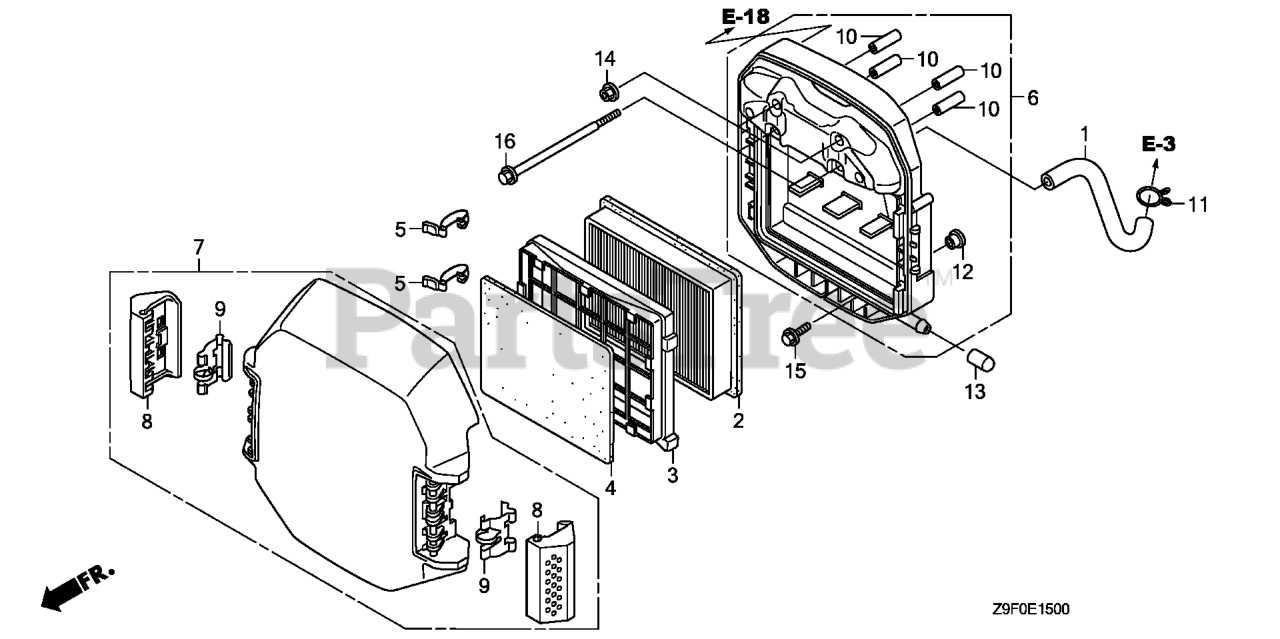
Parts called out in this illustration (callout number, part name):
1	TUBE, BREATHER
2	ELEMENT, AIR CLEANER
3	HOLDER, ELEMENT
4	FILTER (OUTER)
5	CLIP, AIR CLEANER
6	HOUSING, AIR CLEANER
7	COVER, AIR CLEANER
8	KNOB, AIR CLEANER COVER
9	SPRING, AIR CLEANER HOUSING COVER
10	COLLAR, AIR CLEANER
11	CLIP, BREATHER TUBE
12	COLLAR, FAN COVER
13	CAP, SEALING
14	NUT, FLANGE (6MM)
15	BOLT, FLANGE (6X16) Use from Engine SN 2056820.
16	BOLT, FLANGE (6X110)
